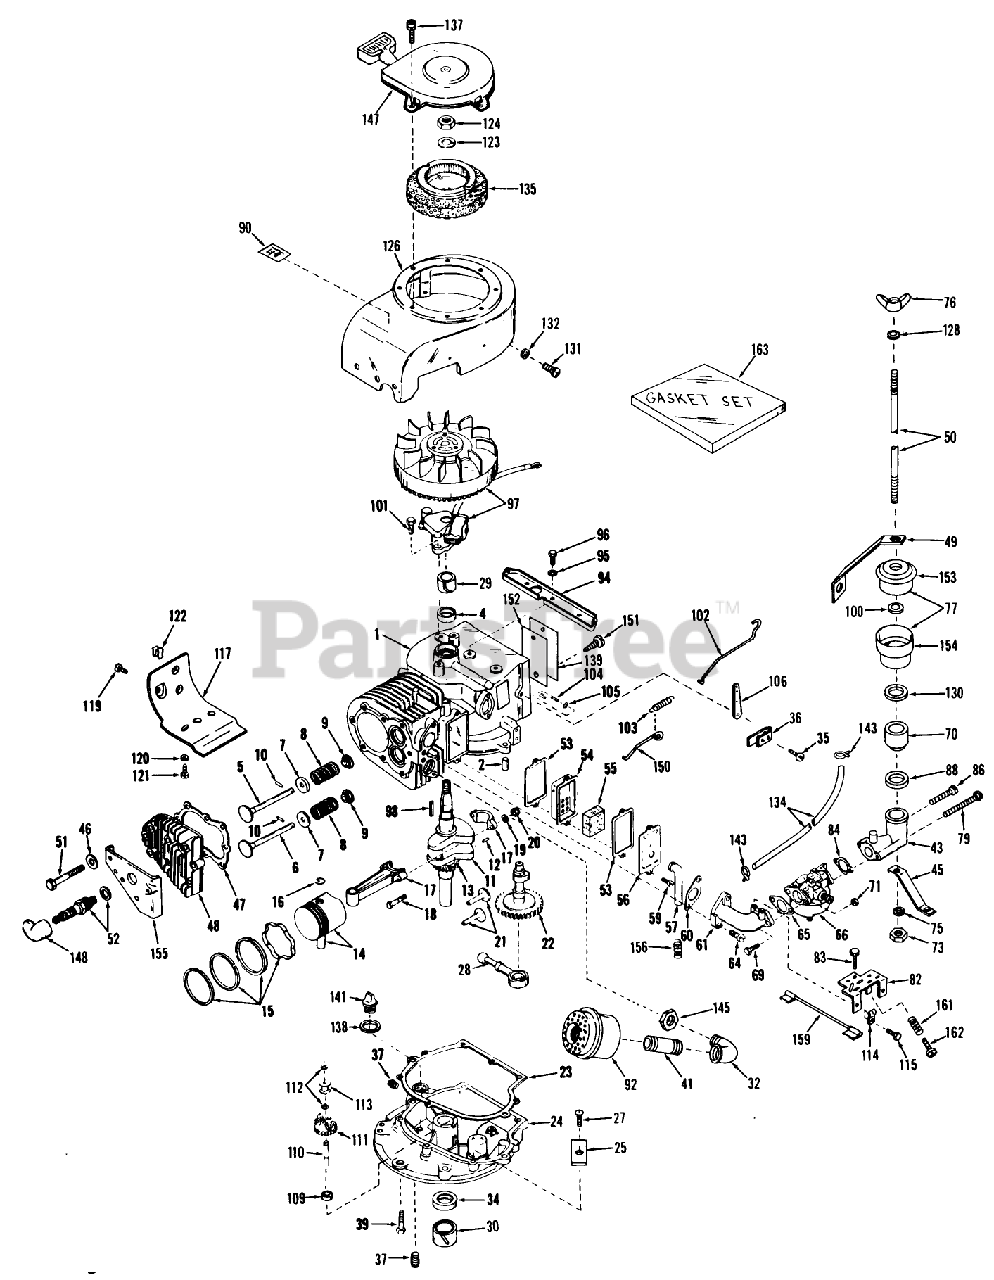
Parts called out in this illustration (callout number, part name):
2	Pin-Dowel
4	Gasket-Crankcase (.005" Thick)
5	Valve, Intake (Standard)
5	Valve, Intake (1/32" oversize)(Incl. Ref. No.9)
6	Valve, Exhaust (Standard)
6	Valve, Exhaust (1/32" overs.)(Incl. Ref. No.9)
7	Cap-Spring, Valve
8	Spring-Valve
9	Cap, Lower valve spring
9	Cap, Lower Valve Spring (1/32" oversize)
10	Pin, Valve spring retaining
11	Crankshaft Assy. (Incl. Ref. Nos.12 13) V40-50008E
11	Crankshaft Assy. (Incl. Ref. Nos.12 13) V40-50037E
12	Pin, Groove
13	Gear-Crankshaft
14	Piston Pin Assy. (Standard)(Incl. (2) of Ref. No.16)
14	Piston Pin Assy. (.0101 oversize)(Incl. (2) of No.16)
14	Piston Pin Assy. (.0201 oversize)(Incl. (2) of No.16)
15	Ring Set, Piston (Standard)
15	Ring Set, Piston (.010 overs.)
15	Ring Set, Piston (.020 overs.)
17	Rod Assy., Connecting (Incl. Nos.18,19 20)
18	Bolt, Connecting Rod
19	Washer
21	Lifter Valve
22	Camshaft
23	Gasket-Cover, Cylinder
24	B Flange Assy., Mounting (Incl. Nos.25, 27, 34, 43 110)
25	Screen-Oil Filter
27	Screw
28	Pump, Oil
29	Bushing, Crankshaft
30	Bushing, Crankshaft
32	Elbow, Exhaust (90 degree)
34	Seal-Oil
35	Screw
36	Clamp-Lever, Governor
37	Plug-Drain, Oil (SQH 1/4-18)
39	Screw (1/4-20 x 1-1/4)
41	Nipple, Pipe
43	Elbow, Air cleaner
45	Brace Cleaner
48	CYLINDER HEAD
49	Brace, Cleaner elbow
50	Stud, Air cleaner
51	Screw
52	SPARK PLUG
53	Gasket-Breather
54	Body-Breather
55	Element-Breather
56	Cover-Valve
57	Tube-Breather
59	Screw
60	Gasket-Intake
61	Pipe, Intake
65	Gasket
70	Spacer, Cleaner
71	Nut and Lock Washer (1/4-28)
75	Lockwasher, Split
76	Nut-Wing
77	Cleaner Assy., Oil Bath Air (Incl. Nos.100,128,130,153 154)
79	Screw
83	Screw (10-24 x 9/16)
84	Gasket
86	KIT - SEAL WIPER
88	Gasket, Spacer
90	Decal, H.P.
92	Muffler
94	Bracket, Blower Housing (Incl. Nos. 131)
95	Lockwasher
96	Screw
97	Magneto
98	Key, Flywheel
100	O Ring
101	Screw
103	Spring Governor
104	Rod, Governor (Incl. Nos. 146)
105	Washer-Flat
106	Lever-Governor
109	Spacer
110	Shaft, Governor
111	Governor Gear ASM
112	Ring-Retaining
113	Spool-Governor
114	Conduit
115	Screw (10-32 x 3/8)
117	Emnsion, Blower Housing
121	Screw
122	51004 GIL ROTARY TI
123	Washer
126	Housing, Blower
128	Washer
130	1565F GIL TILLER.AD
131	Screw
132	Lockwasher
134	Line, Fuel V40-50037E
135	Hub Screen
137	Screw
138	Gasket
141	Plug-Fill, Oil
143	Clamp-Line, Fuel
145	Nut, Conduit
147	Starter, Rewind
148	51005 GIL.ROTARY TI
150	Link, Governor spring
151	Stud
152	IDENTIFICATION PLATE
153	Cover, Oil bath cleaner
154	Bowl, Oil Bath Cleaner
155	Cover, Cylinder head
156	Spring, Coil
159	Wire, Ground
161	Spring-Compression
162	Screw
